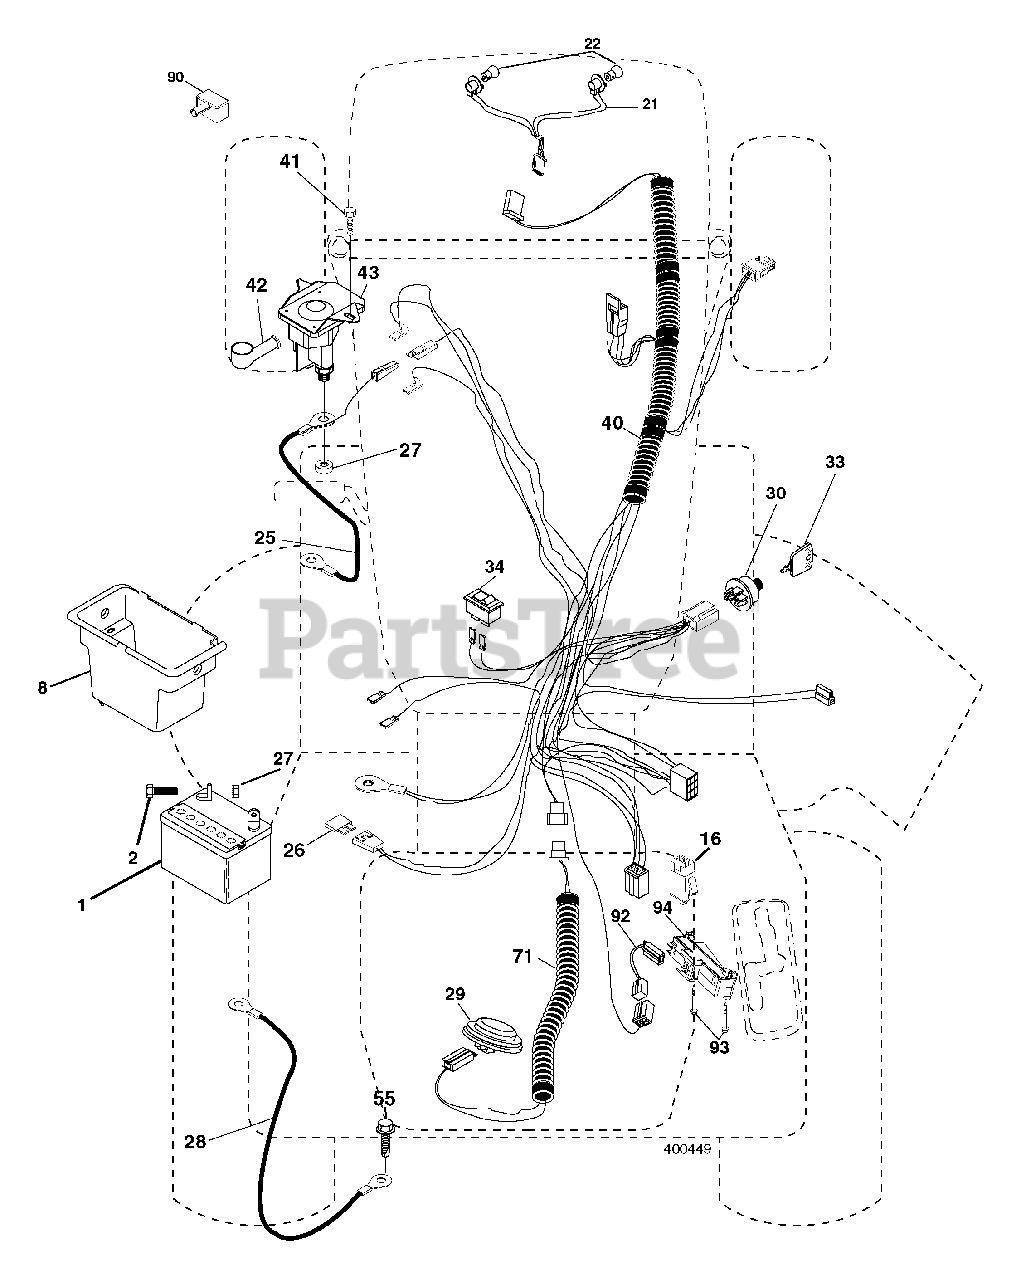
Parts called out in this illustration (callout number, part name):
1	Battery
2	Bolt Hex Head 1/4-20 x 3/4
8	Box Battery
16	Switch Interlock Push-In
21	Harness Socket Light W/4152J
22	Bulb Light
25	Cable Starter
26	Fuse
27	Nut Keps Hex 1/4-20 unc
28	Cable, Ground
29	Switch, Seat
30	Switch, Ignition
33	Key, Ignition
34	Switch Light / Reset
40	Harness Ignition
41	Screw Thd Cut 1/4-20 x 1/2
42	Cover, Terminal
43	Solenoid
55	Screw Thdrol 5/16-18 x 3/4 TYTT
71	Harness Ignition Dash
90	Cover Terminal Battery
92	Harness Pigtail
93	Screw Plastite 10-14 x 2.0
94	Module Reverse ROS
